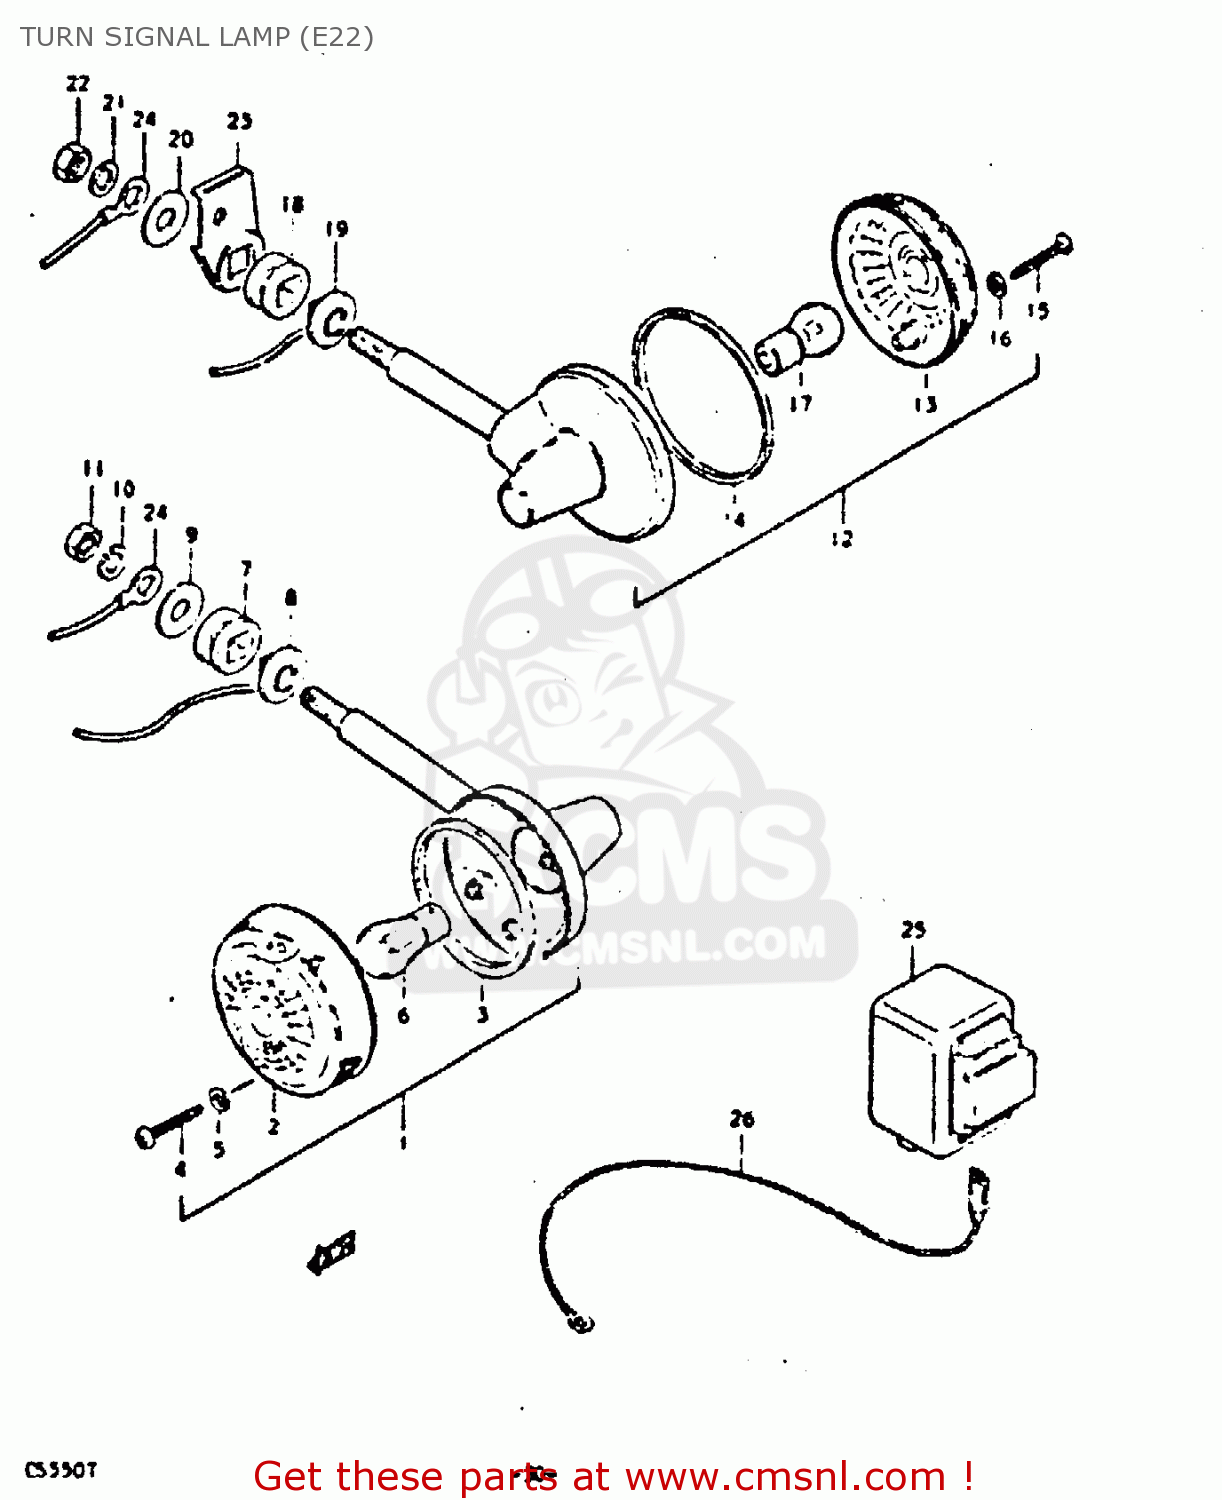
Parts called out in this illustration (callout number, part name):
1	LAMP, FRONT TURN SIGNAL
2	LENS
3	GASKET (NAS)
4	SCREW 4X25
5	GASKET (NAS)
6	BULB(12V21W)
7	CUSHION
8	SPACER
9	WASHER (10.5X30X2.3)
10	LOCK WASHER
11	NUT
12	LAMP, REAR TURN SIGNAL
13	LENS
14	GASKET (NAS)
15	SCREW 4X25
16	GASKET (NAS)
17	BULB(12V21W)
18	CUSHION
19	SPACER
20	WASHER (10.5X30X2.3)
21	LOCK WASHER
22	NUT
23	BRACKET,RR TURNSIGNAL LAMP,R
24	WIRE
25	RELAY, TURN SIGNAL
26	LEAD WIRE, RELAY EARTH
